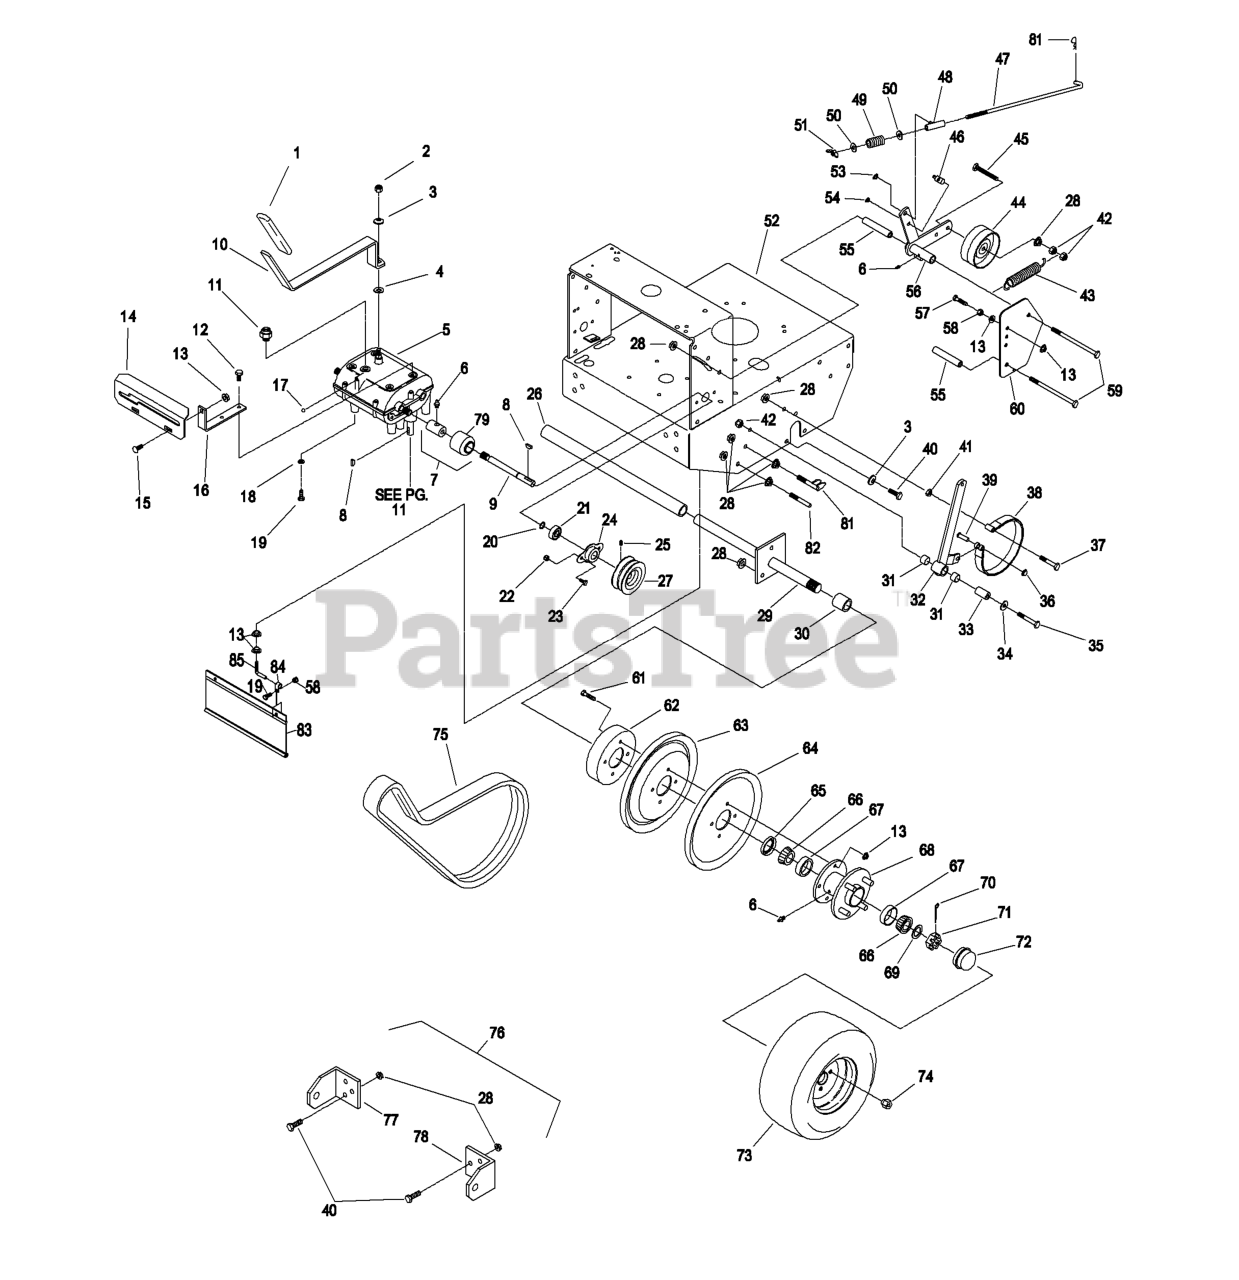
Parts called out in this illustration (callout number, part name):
2	NUT-LOCK
3	WASHER-BELLEVILLE
6	FITTING-GREASE
7	ASM,COUPLER/ZERK
8	KEY-WOODRUFF
9	SHAFT-TRANSMISSION
11	SWITCH-START, NEUTRAL
12	SCREW-HWH, THREAD CUT
15	BOLT-CARR
16	BRACKET-PLATE, SHIFT
17	BALL,DETENT (SERVICE ONL
18	WASHER-LOCK
19	SCREW-HH
20	RING-RETAINING
21	BEARING-SHAFT
22	NUT-LOCK, NI
23	SCREW-HH
24	FLANGE-OUTPUT
25	SCREW-SET
26	SLEEVE,AXLE
28	NUT-HHF, WHIZ
30	SPACER,WHEEL SHORT
31	SLEEVE-BUSHING
33	BUSHING-PIVOT
34	WASHER-FLAT
35	SCREW-HH
36	RING-RETAIN,PUSH,EXT,FLAT
37	SCREW-HH
38	BAND-BRAKE
39	PIN-CLEVIS
40	SCREW-HH
41	NUT-JAM
42	NUT-LOCK, NI
43	SPRING-EXTENSION
44	IDLER-WHEEL, DRIVE
45	SCREW-HH
46	SWIVEL-SHORT, ADJUSTABLE
47	LINKAGE-BRAKE
49	SPRING-COMPRESSION
50	WASHER-PLAIN
51	WINGNUT-NYLOCK
53	RING-RETAINING
54	RING-CLIP
55	SPACER-SHIELD
56	WLD,ARM RH
57	SCREW-HH
58	NUT-LOCK, NI
60	SHIELD,WHEEL DRIVE
61	SCREW-HH
62	DRUM-BRAKE
63	SHEAVE,WHEEL DRIVE
64	SHEAVE,WHEEL DRIVE
65	SEAL-GREASE
66	Cone-Bearing Tapered Roller
67	CUP-BEARING
68	HUB/WHEEL ASM
69	WASHER-SPACER
70	PIN-COTTER
71	NUT-SHH
72	CAP-GREASE
73	WHEEL AND TIRE ASM
74	NUT-LUG
75	BELT,WHEEL DRIVE BANDED
76	Kit, Sulky Hitch
79	GUARD-COUPLER
80	PIN-COTTER
81	SCRAPER
83	SHIELD-TRAILING
84	CLIP-LOOM
85	MOUNT,DRAG SHIELD
